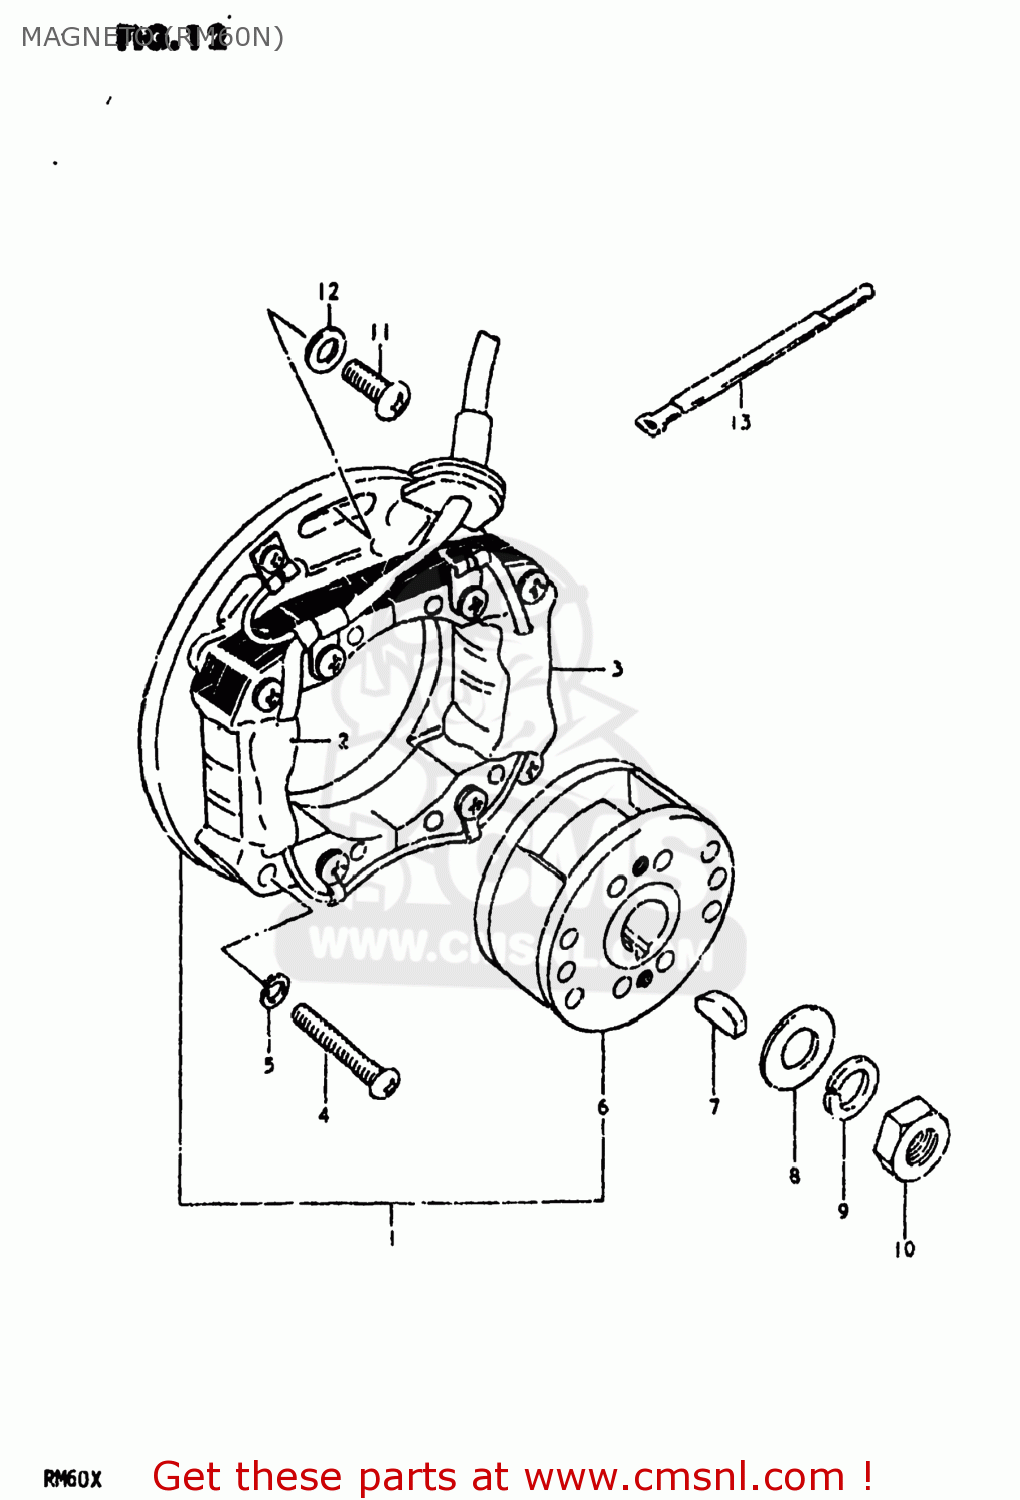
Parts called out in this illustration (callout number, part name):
1	MAGNETO ASSEMBLY
2	COIL,PULSER
3	COIL,PRIMARY
4	SCREW
5	LOCK WASHER
6	ROTOR ASSEMBLY
7	KEY 4MM
8	WASHER
9	LOCK WASHER
10	NUT (10MM)
11	SCREW
12	WASHER
13	CLAMP
